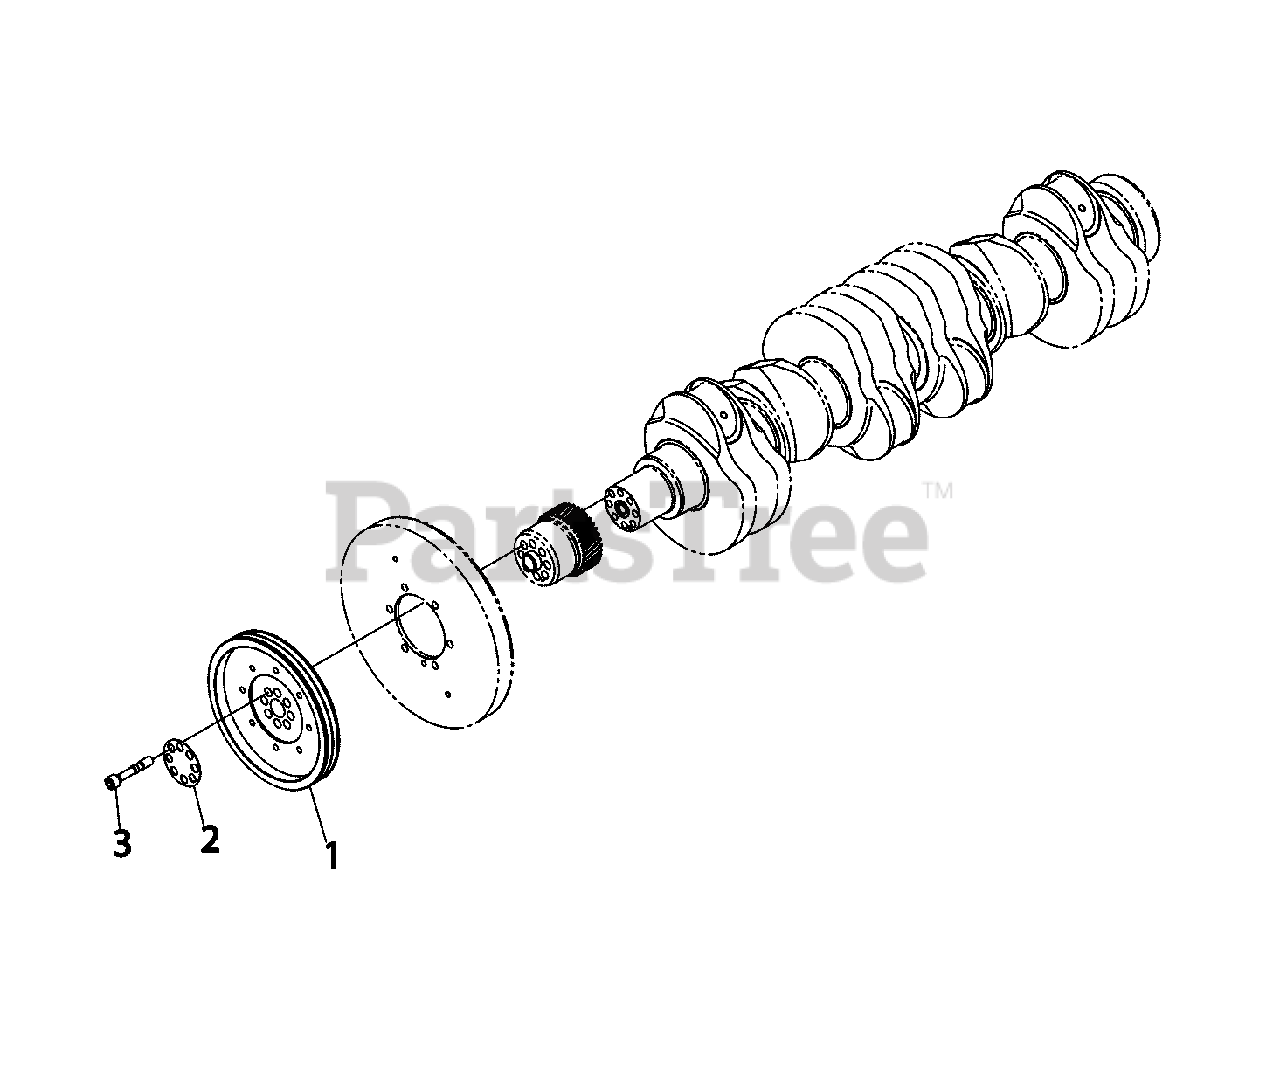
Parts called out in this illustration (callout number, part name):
1	* PULLEY, V-BELT
2	* WASHER
3	* BOLT
